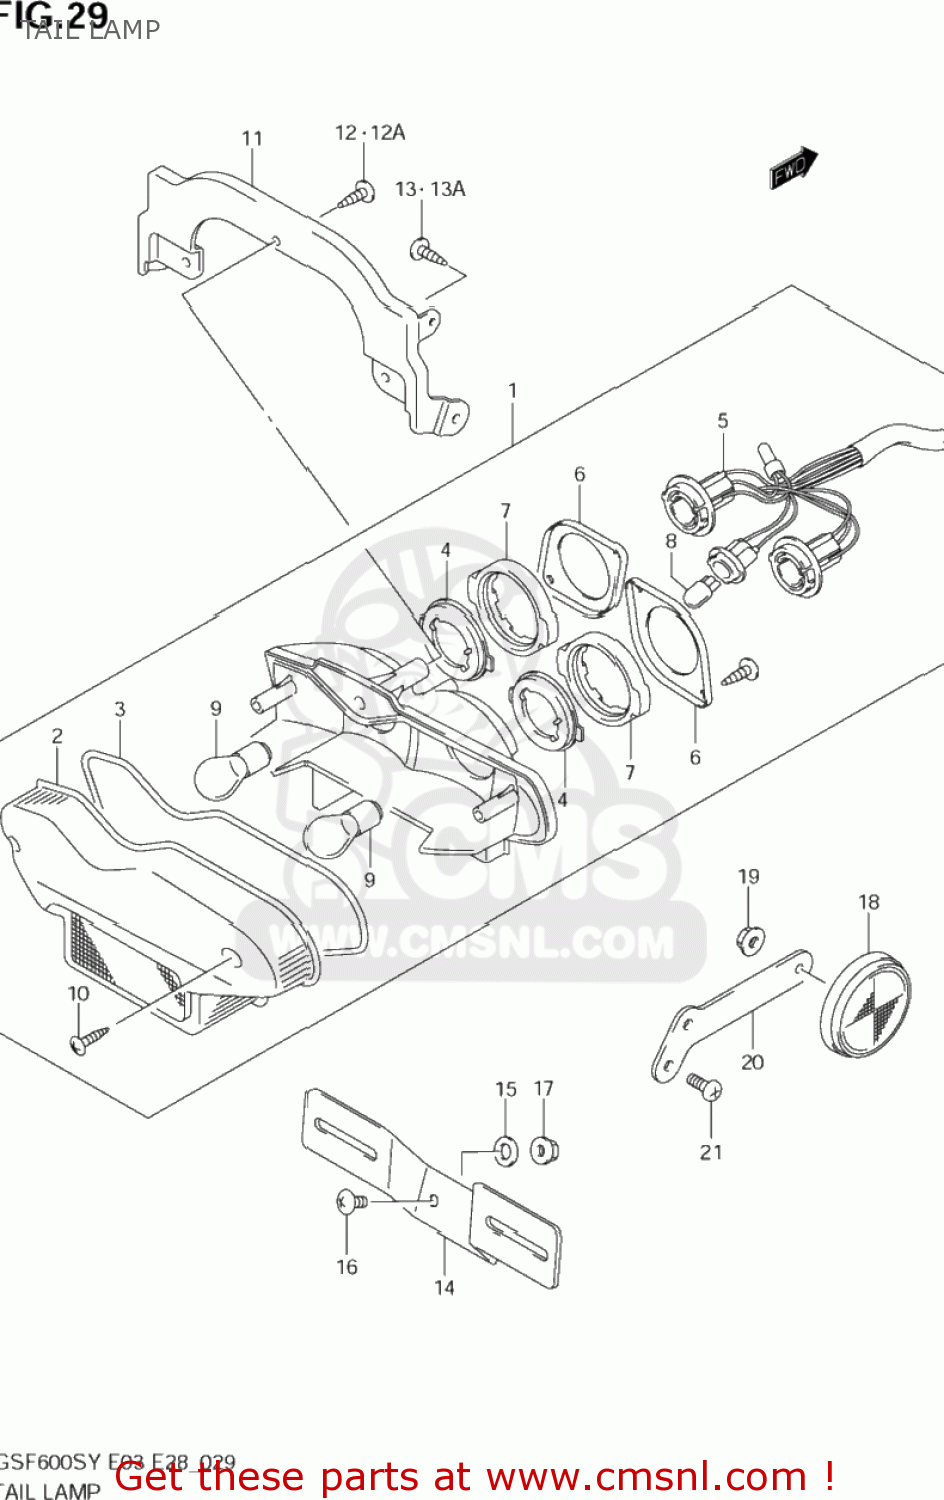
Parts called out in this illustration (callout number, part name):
1	LAMP ASSY,RR COMBINATION
2	LENS
3	GASKET (NAS)
4	PLATE NO.1
5	SOCKET & CORD
6	PLATE NO.2
7	CUSHION
8	BULB(12V5W)
9	BULB(12V21/5W)
10	SCREW
11	BRACKET,RR COMBINATION LAMP
12	SCREW
12A	SCREW(5X16)
13	SCREW
13A	SCREW(5X16)
14	BRACKET,LICENSE PLATE
15	WASHER(6.5X20X1.6)
16	SCREW
17	NUT
18	REFLECTOR ASSY,RR SIDE
19	NUT
20	BRACKET,RR SIDE RR,R
21	SCREW 6X12
